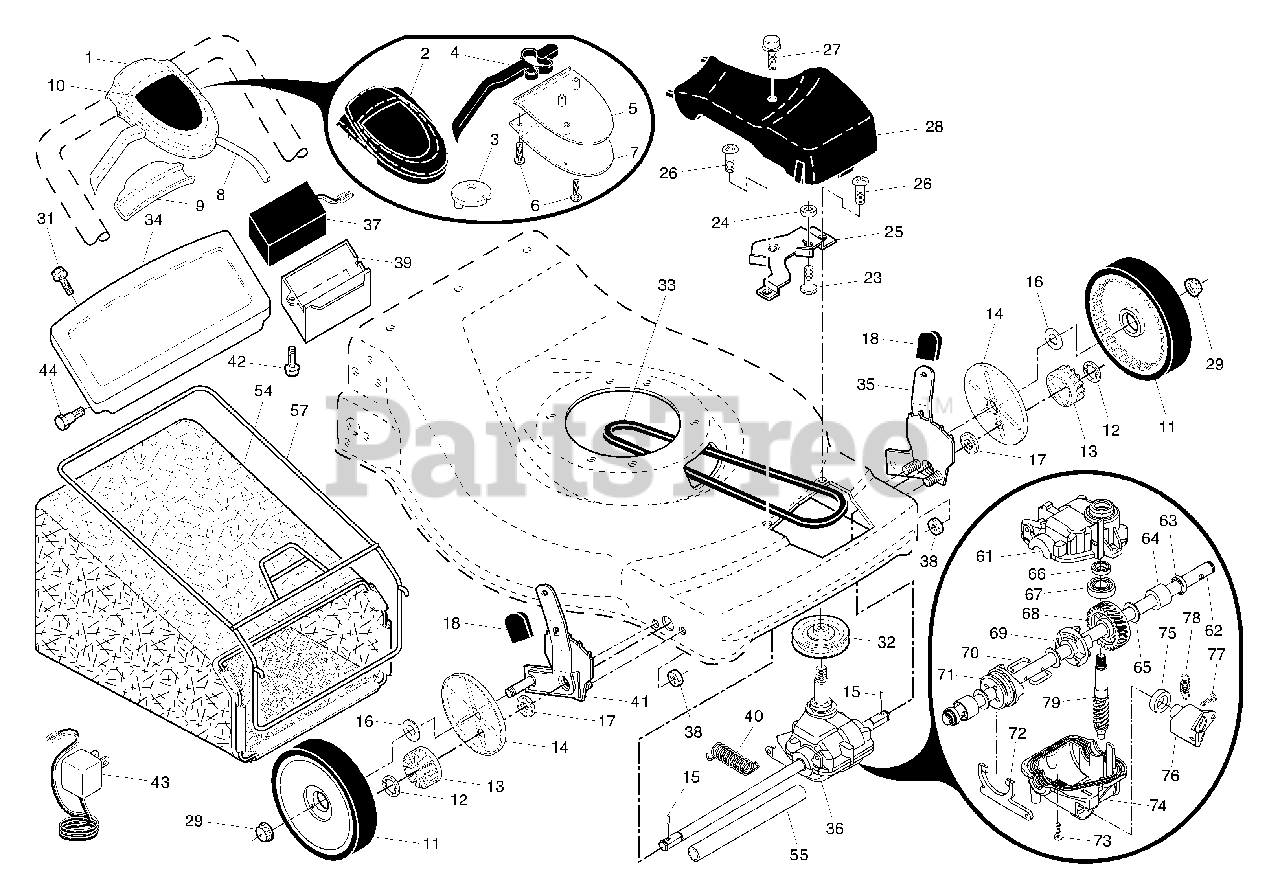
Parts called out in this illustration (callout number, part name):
1	Drive Control Assembly
2	Cover, Drive Control, Top
4	Lever, Drive Control
5	Cover, Drive Control, Bottom
6	Screw, Torx Head #8 x 5/8
7	Mounting Bracket, Drive Control
8	Cable, Drive Control
9	Cap, Drive Control, Bottom
10	Decal, Drive Control
11	Wheel & Tire Assembly
13	Gear, Pinion
14	Dust Cover
15	Drive Pawl
16	Washer, Flat 3/8
17	Bearing, Wheel Adjuster
18	Selector Knob
25	Belt Guide Bracket
27	Pan Head Tapping Screw #10-24 x 2-3/4
28	Drive Cover
29	Locknut, Hex
31	Screw, Trimplate, Top
32	Drive Pulley
34	Trimplate
35	Kit, Wheel Adjuster, LH
36	Gearcase Assembly, Complete
37	Battery
38	Locknut, Hex 1/4-20
39	Box, Battery
41	Kit, Wheel Adjuster, RH
42	Screw, Battery Box
43	Charger, Battery
44	Screw, Shoulder, Hex Head #10 x 9/32 x 1/16
54	Grassbag Assembly
55	Driveshaft Cover
57	Frame, Grassbag
61	Case, Upper
62	Shaft, Output
63	Seal, Output Shaft
66	Seal, Worm Shaft
67	Bearing, Ball
68	Gear, 27 Teeth
69	Fixed Dog Clutch
71	Movable Dog Clutch
73	Screw, Case
74	Case, Lower
75	Seal, Lever
77	Screw, Lever
79	Shaft, Worm
